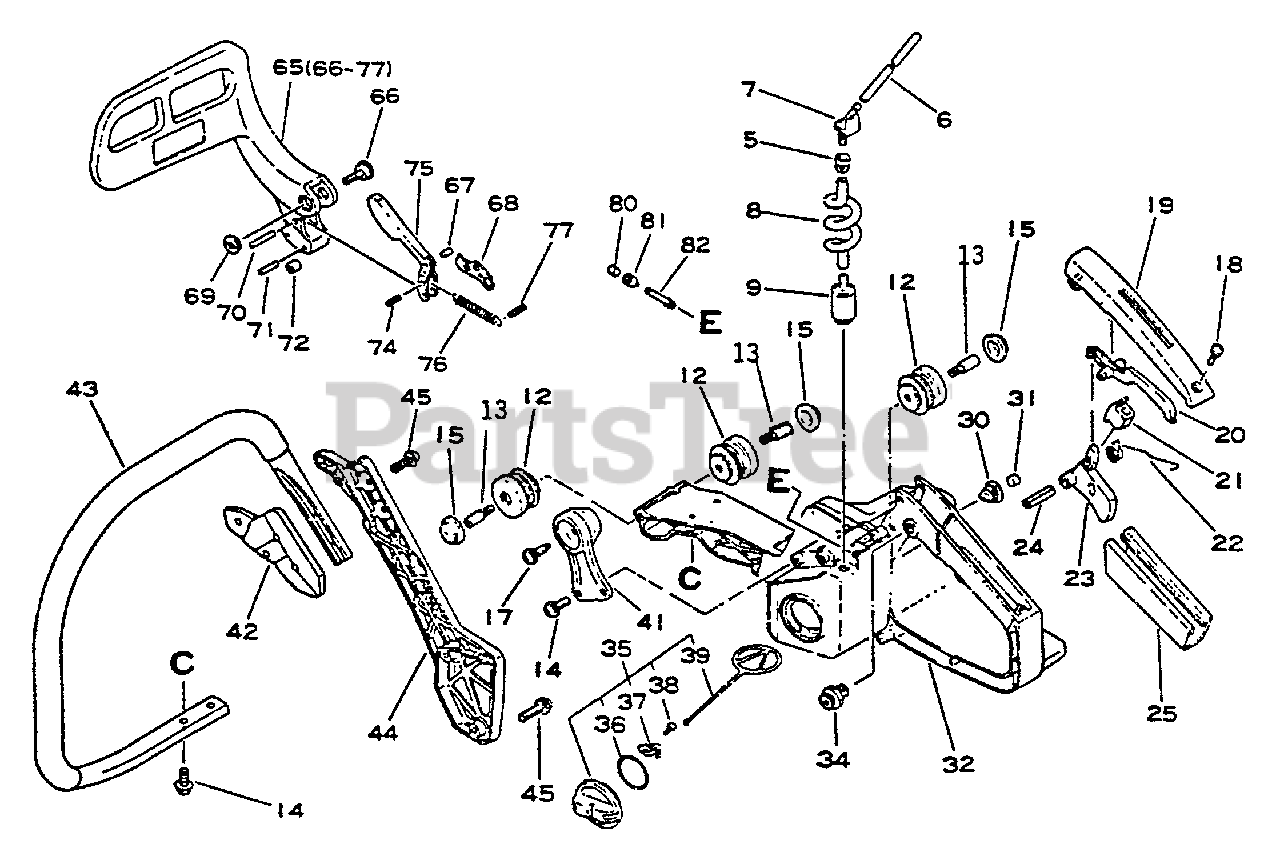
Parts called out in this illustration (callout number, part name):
5	GROMMET
6	PIPE, FUEL - 3×6×100
7	CONNECTOR, PIPE
8	PIPE, FUEL
9	FILTER, FUEL
12	CUSHION
13	SCREW
14	SCREW - 5×14
15	CAP, CUSHION
17	SCREW - 5×14
18	SCREW - 4×14
19	COVER, HANDLE
20	CONTROL, THROTTLE
21	CUSHION, THROTTLE
22	SPRING, THROTTLE RETURN
23	TRIGGER, THROTTLE - BLACK
24	PIN, SPRING
30	VENT ASSY
31	FILTER, CHECK VALVE
32	HANDLE - REAR
34	LOCK, THROTTLE
35	CAP ASSY
36	O-RING 29
37	RETAINER, CONNECTOR
38	SCREW 3×8
39	CONNECTOR, CAP L= 60 MM
41	CUSHION
42	BRACKET, HANDLE
43	HANDLE, FRONT
44	BRACKET, HANDLE - OUTER
45	SCREW - 5×20
65	BRAKE LEVER ASSY
67	PIN, LOCATING 4×8
68	STOPPER
70	PIN 3×24
71	PIN 3×18
72	SPACER
74	PIN, SPRING 3×12
75	WEIGHT, BRAKE
76	SPRING, RETURN
77	PIN, SPRING 30×20
80	VENT ASSY
81	HOLDER, VENT
82	PIPE, VENT
84	SCREW
